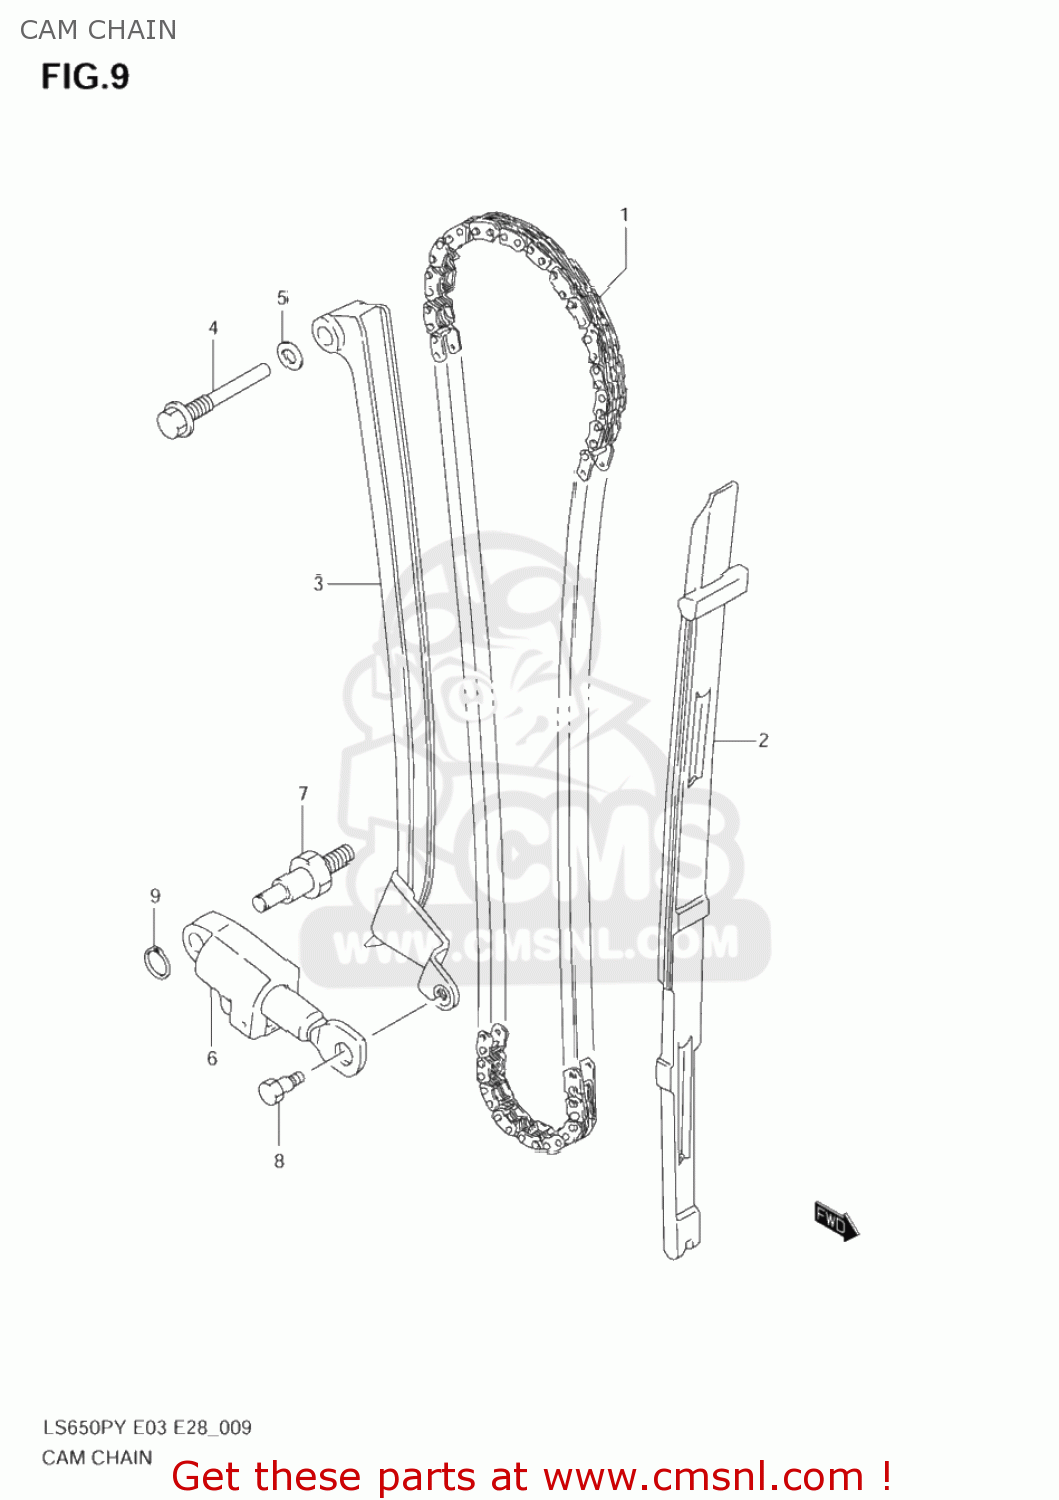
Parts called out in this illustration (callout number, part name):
1	CHAIN,CAMSHAFT DRIVE
2	GUIDE,CAM CHAIN
3	TENSIONER,CAM CHAIN
4	BOLT,CAM CHAIN TENSIONER
5	GASKET 8.2X14X1 (NAS)
6	ADJUSTER ASSY,TENSIONER
7	BOLT,STUD
8	BOLT
9	CIRCLIP
